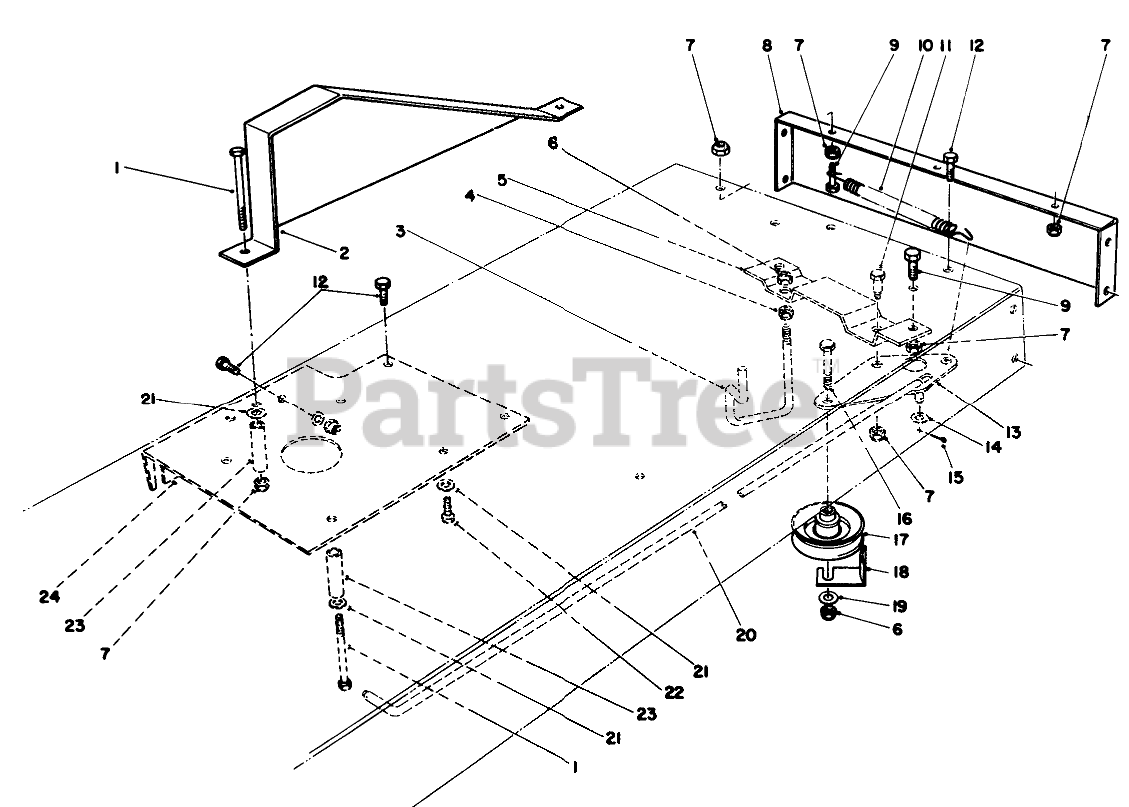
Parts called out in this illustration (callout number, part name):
1	SCREW-HH
2	CHAIN GUARD R
3	BELT GUIDE
4	NUT-LOCK, SIDE
5	TRACT SUPP BRKT B
6	NUT-LOCK, CONE
7	NUT-LOCK, NI
8	REAR FRAME R
9	SCREW-HH
10	TRACTION SPRING
11	BOLT-SHOULDER
12	SCREW-HH
13	TRACTION PIVOT BRKT
14	WASHER-FLAT
15	PIN-COTTER
16	SCREW-HH
17	PULLEY-IDLER
18	RETAINER-BELT
19	WASHER-FLAT
20	TRACTION ROD
21	WASHER-PLAIN
22	Screw-HH
23	OUTER TUBE SPACER
24	REINF PLATE R
